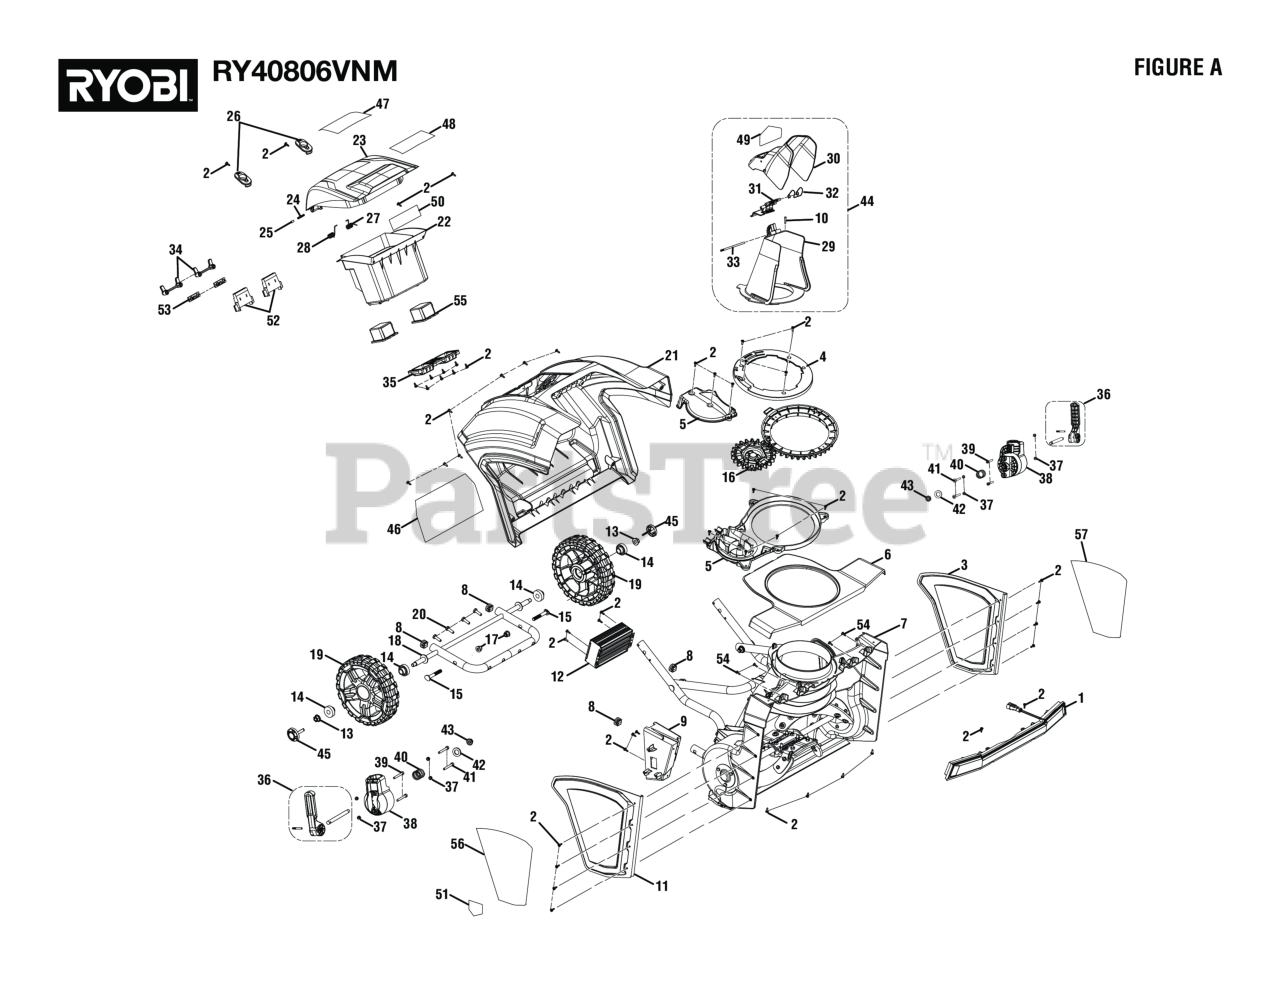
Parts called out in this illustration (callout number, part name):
1	LED Light Assembly
2	Screw (M4.2 x 12 mm, T20 Torx Pan Hd.)
3	Left Side Cover
4	Chute Rotation Bezel
5	Chute Rotation Assembly
6	Top Housing Cover
7	Auger Housing Assembly
9	Mount Assembly
10	Screw (M4 x 20 mm, Philllips -Pan Hd., RY40806VNM)
11	Right Side Cover Assembly
12	Brushless Motor Controller
13	Lock Nut (3/8-16, Flange)
14	Wheel Spacer
15	Bolt (M8 x 60 mm, Pan Hd.)
16	Chute Gear Assembly
17	Flange Lock Nut (M8 x 1.25 mm)
18	Axle and Lower Frame Assembly
19	8 in. Wheel Assembly
20	Screw (1/4-15 x 3/4 in., T30 Torx Pan Hd.)
21	Rear Cover Assembly
22	Battery Box Assembly
23	Battery Cover Assembly
24	Compression Spring
25	Battery Door Axle
27	Torsion Spring (RH)
28	Torsion Spring (LH)
29	Upper Chute
30	Chute Deflector
32	Chute Deflector Spring
33	Pin (Deflector)
34	Pin (Latch)
35	Spring Retainer
36	Cam Latch Assembly
38	Knuckle Assembly
39	Cap Screw (M5 x 45 mm, T25 Torx Soc. Hd.)
40	Compression Spring
41	Screw (M5 x 35 mm, T25 Torx Pan Hd.)
42	Washer (OD24 x ID12.5 x 2.5t)
43	Flange Nut (M8, Flywheel)
44	Chute Deflector Assembly w/Label
45	Wheel Hub
46	Data/Warning Icons Label
47	Battery Notice Label
48	Logo Label (Battery Cover)
49	Chute Warning Icons Label
50	Recommended Battery Usage Label
51	Danger Label (No Hands/Feet)
52	Battery Connector
53	PLASTIC, BATTERY COVER CONNECTOR,
54	Screw (M3 x 8 mm, Pan Hd., Pan Hd)
55	Battery Ejector Post
56	Hold-Down Tab
57	LABEL, RIGHT SIDE DIE CUT VINYL GRAPHICS
58	LABEL, LEFT SIDE DIE CUT VINYL GRAPHICS
